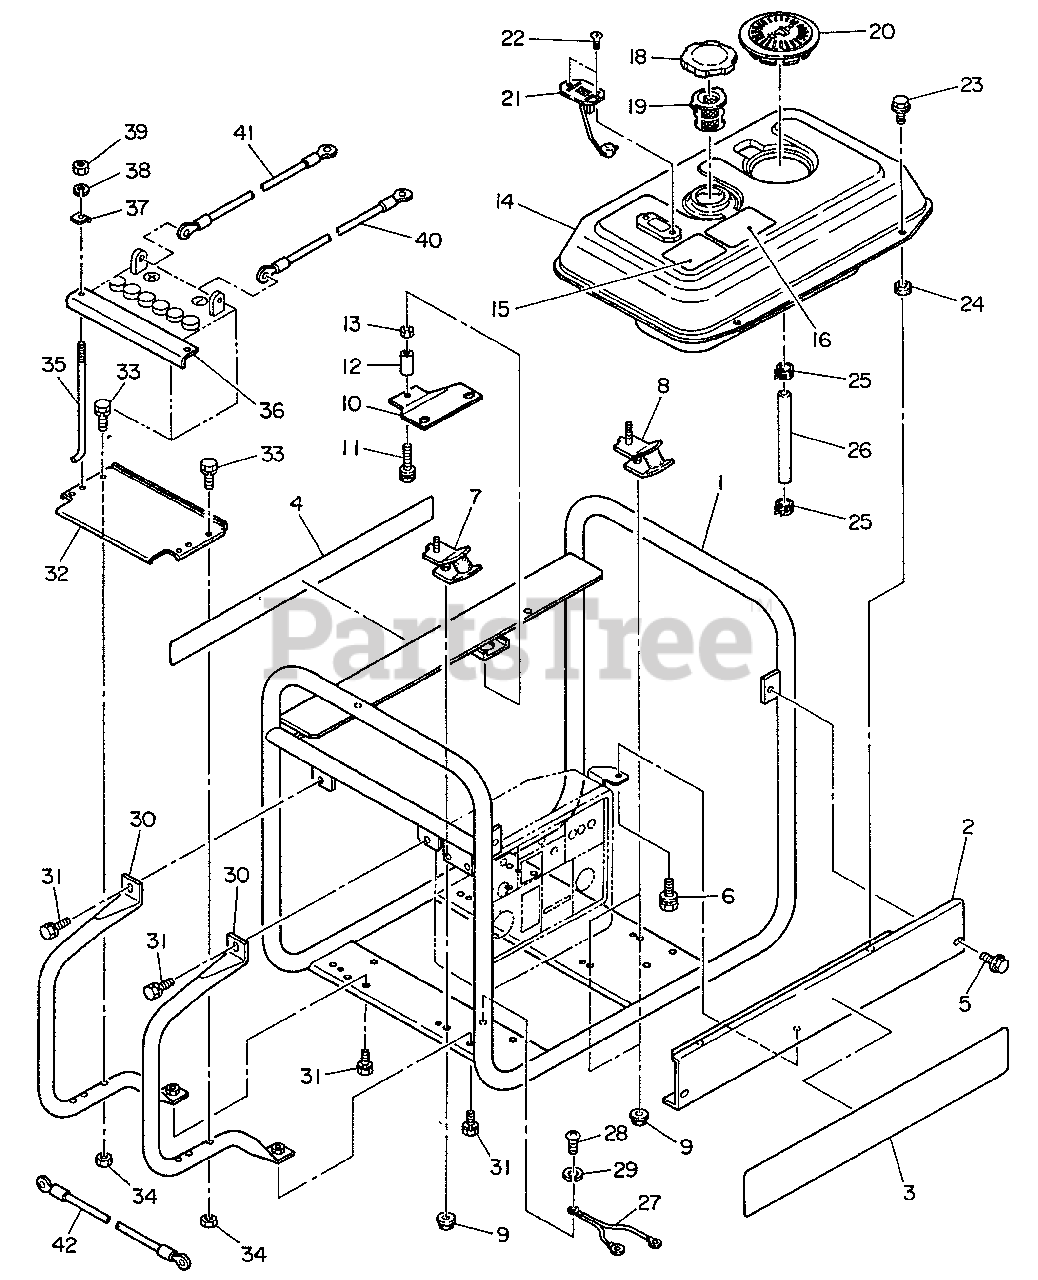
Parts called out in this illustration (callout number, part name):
1	PIPE FRAME ASSY
2	SIDE PLATE ASSY
3	LABEL - MODEL EG-5500E
4	LABEL - MODEL EG-5500E
5	BOLT - FLANGE
6	BOLT
7	MOUNT, RUBBER
8	MOUNT, RUBBER
9	NUT - 8 -- FLANGE
10	STOPPER PLATE
11	BOLT
12	SPACER
13	NUT
14	FUEL TANK ASSY
15	LABEL - CAUTION -- OPERATION
16	LABEL - DANGER
19	FILTER, FUEL
20	COVER
21	FUEL GAUGE ASSY
22	SCREW
23	BOLT - FLANGE
24	WASHER - RUBBER
25	CLAMP, HOSE
26	RUBBER PIPE (11.5 X 17.5 X 230mm)
27	LEAD - GROUND
28	SCREW
29	LOCKWASHER
30	BATTERY FRAME ASSY
31	BOLT
32	BASE, BATTERY
33	BOLT
34	NUT
35	BOLT
36	BATTERY RETAINER
37	BATTERY SUPPORT
38	LOCKWASHER
39	NUT
40	BATTERY CORD (-)
41	BATTERY CORD (+)
42	BATTERY CORD (+)
